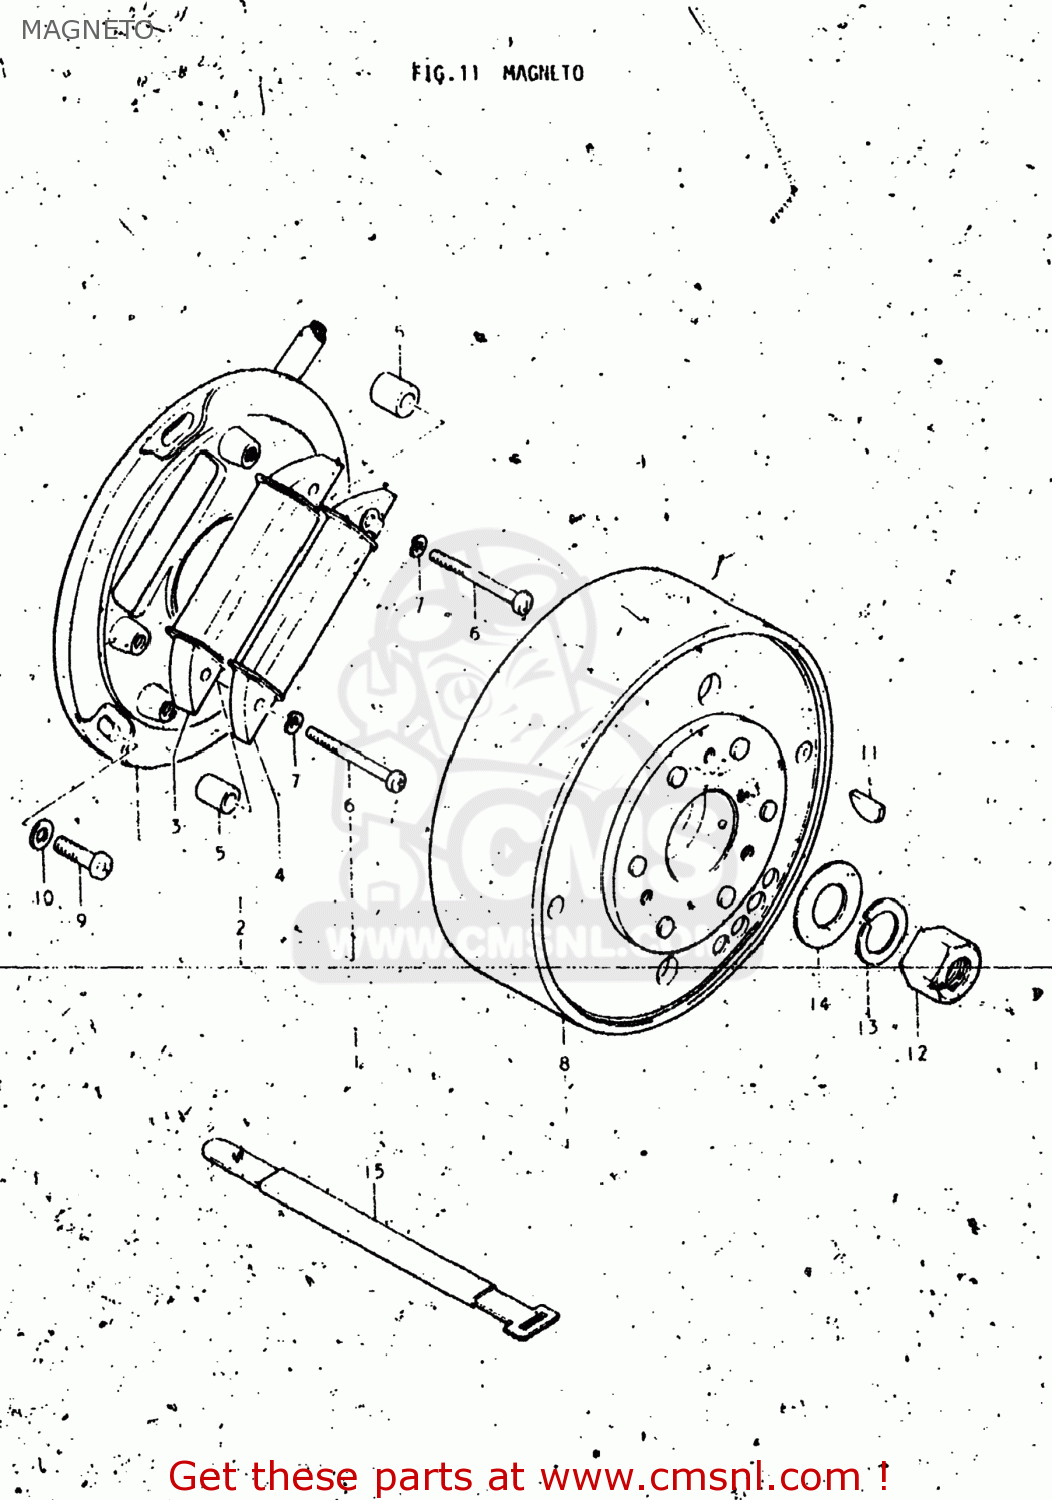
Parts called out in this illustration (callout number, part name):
1	MAGNETO ASSEMBLY
2	STATOR ASSEMBLY
3	COIL
4	COIL,PULSER
5	COIL ASSEMBLY,PICK-UP
6	SCREW 5X35
7	LOCK WASHER
8	ROTOR ASSEMBLY
9	SCREW
10	WASHER
11	KEY 4MM
12	NUT
13	LOCK WASHER
14	WASHER(14X27X3)
15	CLAMP
